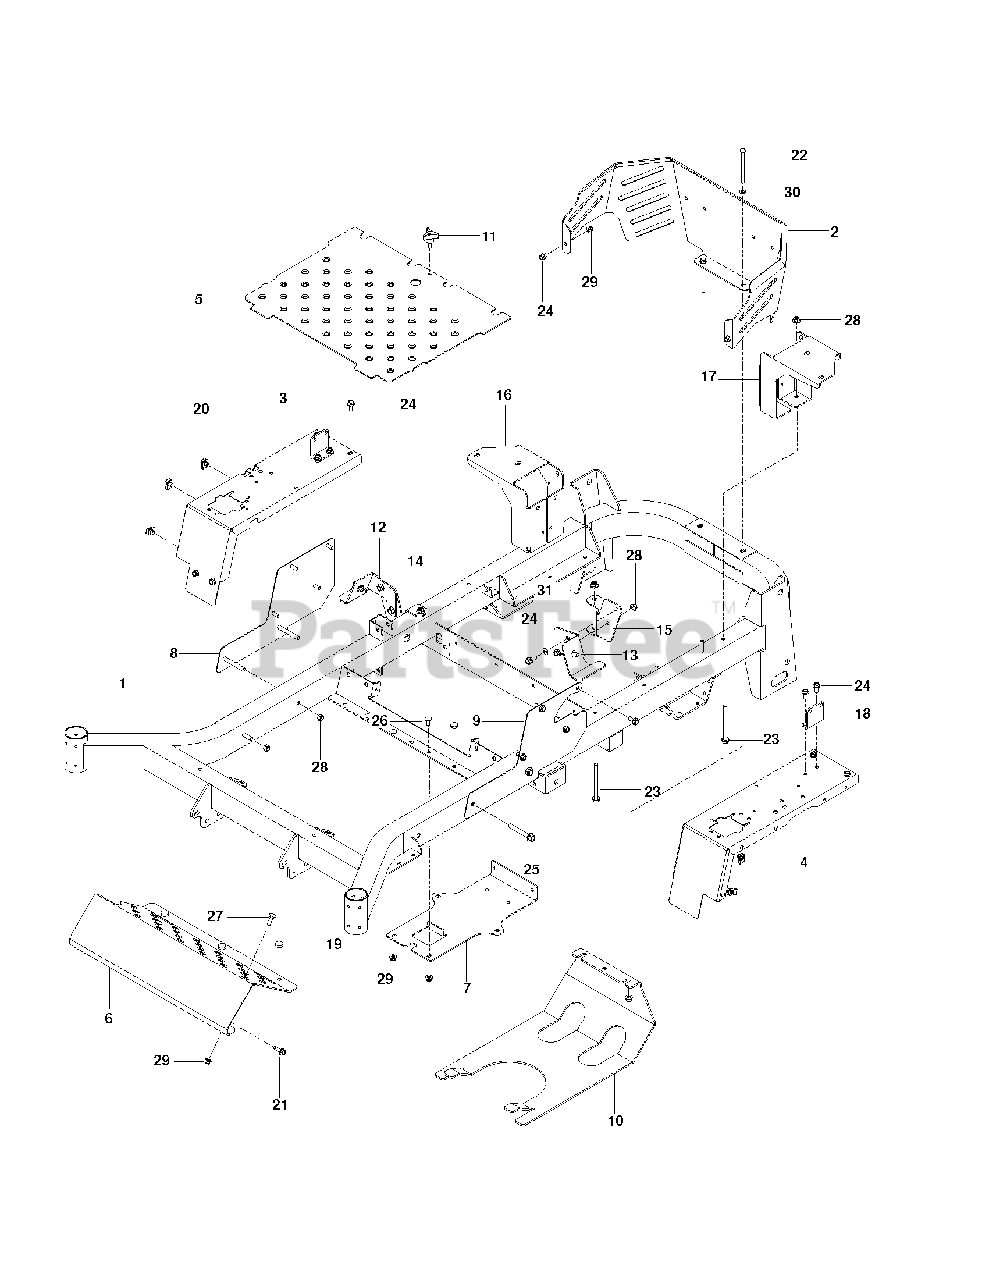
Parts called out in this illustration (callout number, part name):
5	FLOOR PAN W/DECALS
6	PLATE, FOOT REST - RAM DK BLUE
7	PLATE, BATTERY, BLACK
8	SIDE, RT, BL
9	SIDE, LT, BL
10	GUARD, SKID, BLUE
11	KNOB W/STUD
12	MOUNT, TANK, RT-BLK
13	MOUNT, TANK, LT-BLK
14	SUPPORT FRONT TANK R BLK
15	SUPPORT FRONT TANK L BLK
16	SUPPORT REAR TANK R BLK
17	SUPPORT REAR TANK L BLK
19	GROMMET, BUMPER
20	U-CLIP 5/16-18 NUT RETAINER
22	HCS 5/16C X 4
23	HHFS 5/16-18 X 3 3/4
24	HHFS 5/16-18 X 3/4
25	HHFS 3/8-16 X 2 3/4
26	BOLT 5/16C X 3/4" CARRIAGE
27	RHSNB 5/16C X 1
28	NUT HEX 3/8-16 NYLON, THIN
29	5/16-18 NYLOC FLANGE NUT
30	FLAT WASHER 5/16 SAE
31	WASH 5/16 DISC SPRING ZD
